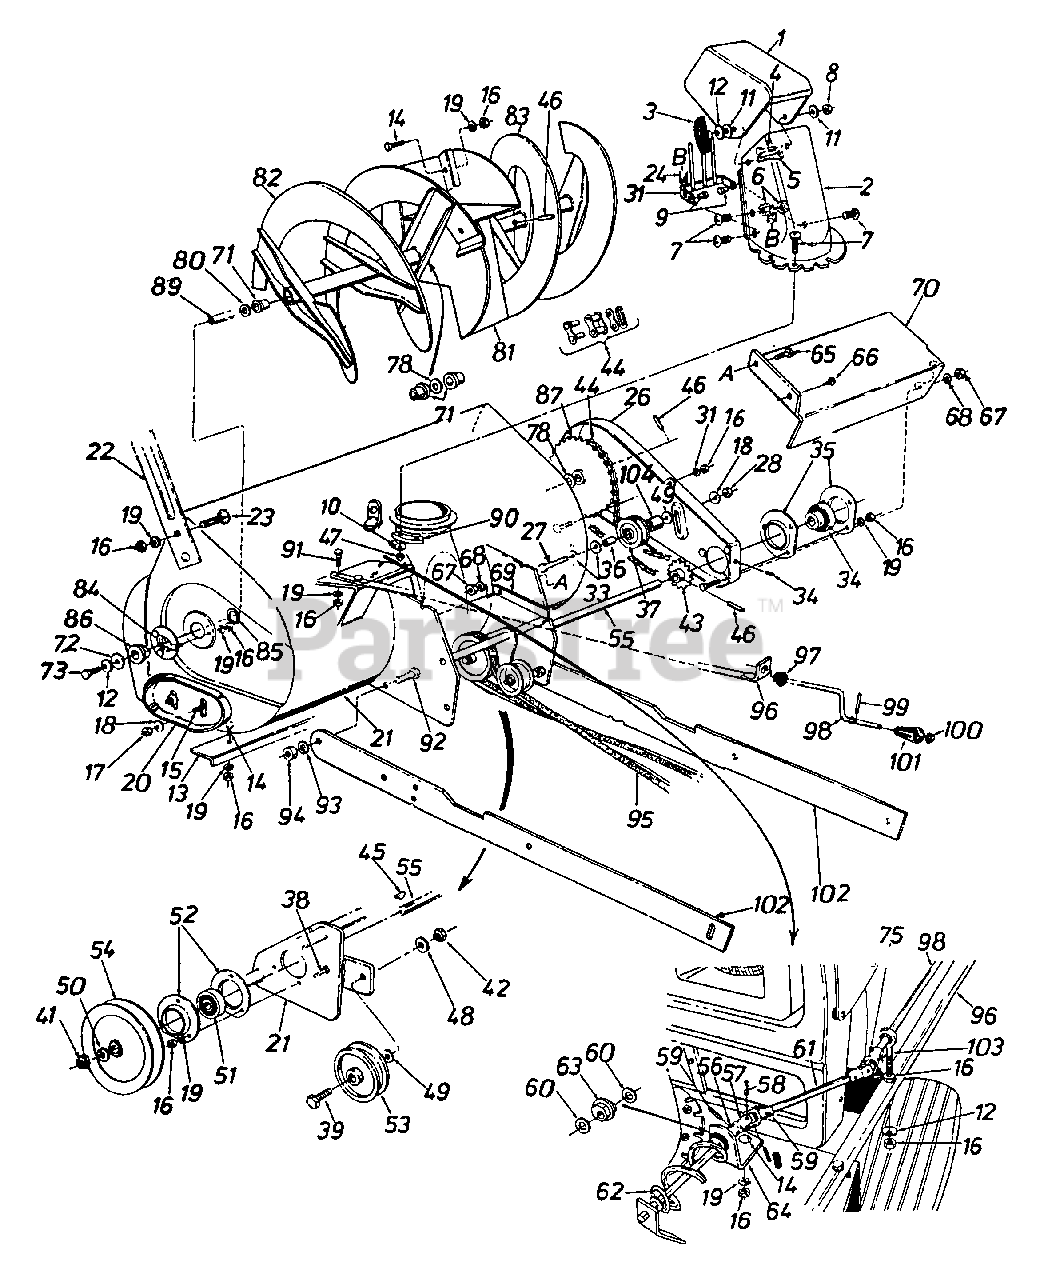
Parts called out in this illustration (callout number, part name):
1	Upper Chute
2	Lower Chute
3	Knob Handle Ass'y.
4	Truss Mach. Scr. 5/16-18 x .75" Lg.
5	Carriage Bolt 5/16-18 x 1" Lg.
6	Hex Cent. L-Nut 5/16-18 Thd.
7	Truss Mach. Scr. 1/4-20 x .75" Lg.
8	Hex Cent. L-Nut 5/16-18 Thd.
9	Shld. Nut 1/4-20 Thd.
10	Fl-Wash. 1/4" I.D.
11	Fl-Wash. .344" I.D. x 1.125"
12	Bell-Wash. .345" I.D. x .88"
14	Carriage Bolt 5/16-18 x .62" Lg.
15	Carriage Bolt 3/8-16 x .62" Lg.
16	Hex Nut 5/16-18 Thd.
17	Hex Jam Nut 3/8-16 Thd.
18	Bell-Wash. .40" I.D. x .88"
19	L-Wash. 5/16" I.D.
20	Slide Shoe
21	Spiral Hsg. Ass'y. - 36"
23	Carriage Bolt 5/16-18 x .62"
24	Extension Spring
26	Chain Guard Ass'y.
27	Hex Bolt 3/8-16 x 2" Lg.
28	Hex Ins. Nut 3/8-16 Thd.
33	Fl-Wash. .385" I.D. x .87" O.D.
34	Ball Brg. .75" I.D.
35	Flangette
36	Spacer .375" I.D. x .60" O.D.
37	Flat Idler 1.875" Dia.
38	Hex Sems Bolt 5/18 x .75" Lg.
39	Hex Bolt 3/8-16 x 1.75" Lg.
41	Hex Jam Nut 3/4-10 Thd.
42	Hex Jam Nut 3/8-16 Thd.
43	Sprocket Ass'y. - 14 Teeth
44	#420 Chain x 1/2" Pitch - 77 Links
45	#61 Hi-Pro-Key 3/16 x 5/8"
46	Spring Pin Spir. 5/16" Dia. x 1.75" Lg.
47	Hex L-Nut 1/4-20 Thd.
48	L-Wash. 3/8" I.D.
49	Fl-Wash. .406" I.D. x 1.25"
50	Spr. L-Wash. 3/4" I.D.
51	Self-Aligning Brg.
52	Flangette
53	Idler Pulley
54	5/8 V-Pulley .75" I.D. x 6" O.D.
55	Drive Shaft Ass'y.
56	Joint Brkt. Ass'y.
57	Joint Block
58	Oval Head Rivet
59	Spiral Pin 1/8" Dia.
60	Fl-Wash. .385" I.D. x .62"
61	Chute Crank Ext. Rod
62	Chute Crank Ass'y. R.H.
63	Plastic Bushing .38" I.D.
64	Chute Crank Brkt.
65	Hex Bolt 1/4-20 x .62" Lg.
66	Hex Wash. S-Tap Scr. 1/4-20 x .50" Lg.
67	Hex Nut 1/4-20 Thd.
68	L-Wash. 1/4" I.D.
69	Belt Cover
70	Drive Shaft Cover
71	Plastic Bushing
72	Washer .39" I.D. x 1.75" O.D.
73	Hex Bolt 5/16-18 x .88" Spec.
75	Cotter Pin 3/32" Dia.
78	Fl-Wash. 1.03" I.D. x 1.62"
80	Fl-Wash. 1" I.D. x 1.75"
85	Snap Ring for 1.5" Shaft
86	Flange Brg. w/flats 1" I.D.
87	Sprocket Hub Ass'y. 40 Teeth
89	Spiral Axle
90	Chute Flange Keeper
91	Hex Bolt 5/16-18 x 1.5" Lg.
92	Hex Bolt 1/2-13 x 1.25" Lg.
93	L-Wash. 1/2" I.D.
94	Hex Nut 1/2-13 Thd.
95	"V"-Belt
98	Chute Crank 34.5" Lg.
99	Roll Pin .12" Dia. x .63"
100	Push Nut 3/8" Rod
101	Knob Black
102	Linkage Arm
103	Eye Bolt 5/16-18 x 3" Lg.
104	Idler Spacer
